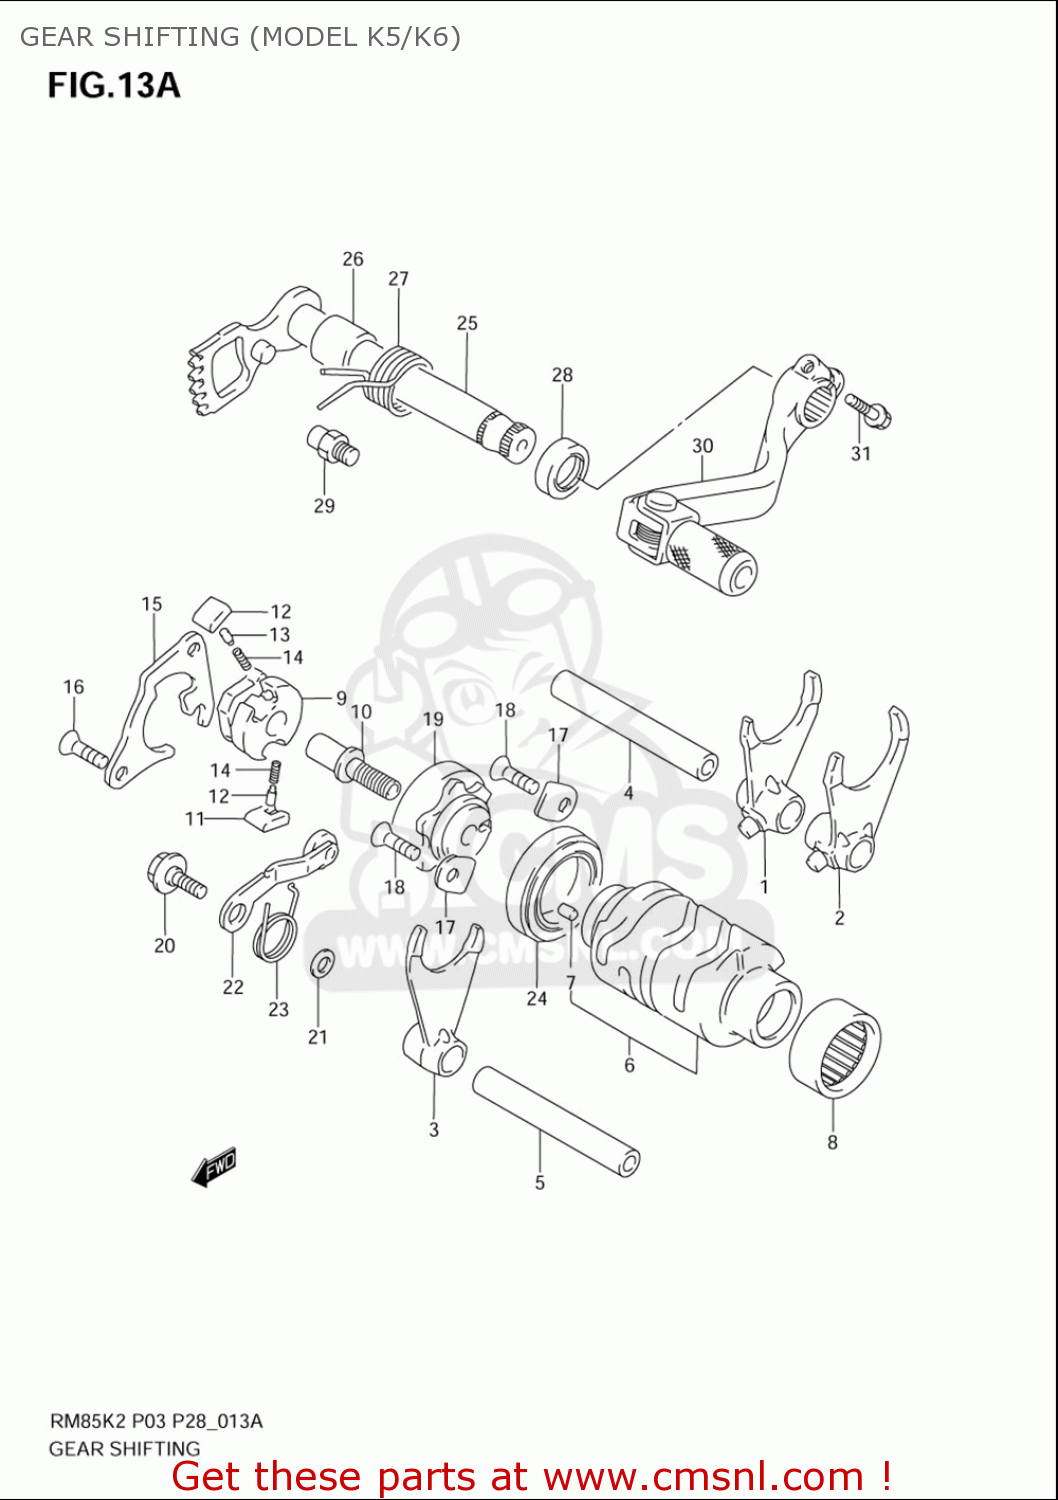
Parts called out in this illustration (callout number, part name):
1	FORK,GEAR SHIFT NO.1
2	FORK,GEAR SHIFT NO.2
3	FORK,GEAR SHIFT NO.3
4	SHAFT,GEAR SHIFT FORK NO.1
5	SHAFT,GEAR SHIFT FORK(L:60)
6	CAM,GEAR SHIFT
7	PIN
8	BEARING(25X32X12)
9	GEAR,GEAR SHIFT CAM DRIVEN
10	PIN,SHIFT CAM DRIVEN GEAR
11	PAWL,GEAR SHIFT NO.1
12	PAWL,GEAR SHIFT NO.2
13	PIN
14	SPRING
15	LIFTER,GEAR SHIFT POLE
16	SCREW(6X12)
17	RETAINER,COUNTER BEARING,R
18	SCREW(6X12)
19	PLATE,SHIFT CAM STOPPER
20	BOLT(6X14.3)
21	WASHER
22	STOPPER,SHIFT CAM
23	SPRING,SHIFT CAM STOPPER
24	BEARING
25	SHAFT,GEAR SHIFT
26	SPACER(14X20X17.5)
27	SPRING
28	SEAL,OIL(14X22X6)
29	STOPPER,GEAR SHIFT ARM
30	LEVER ASSY,GEAR SHIFT
31	BOLT,6X20
